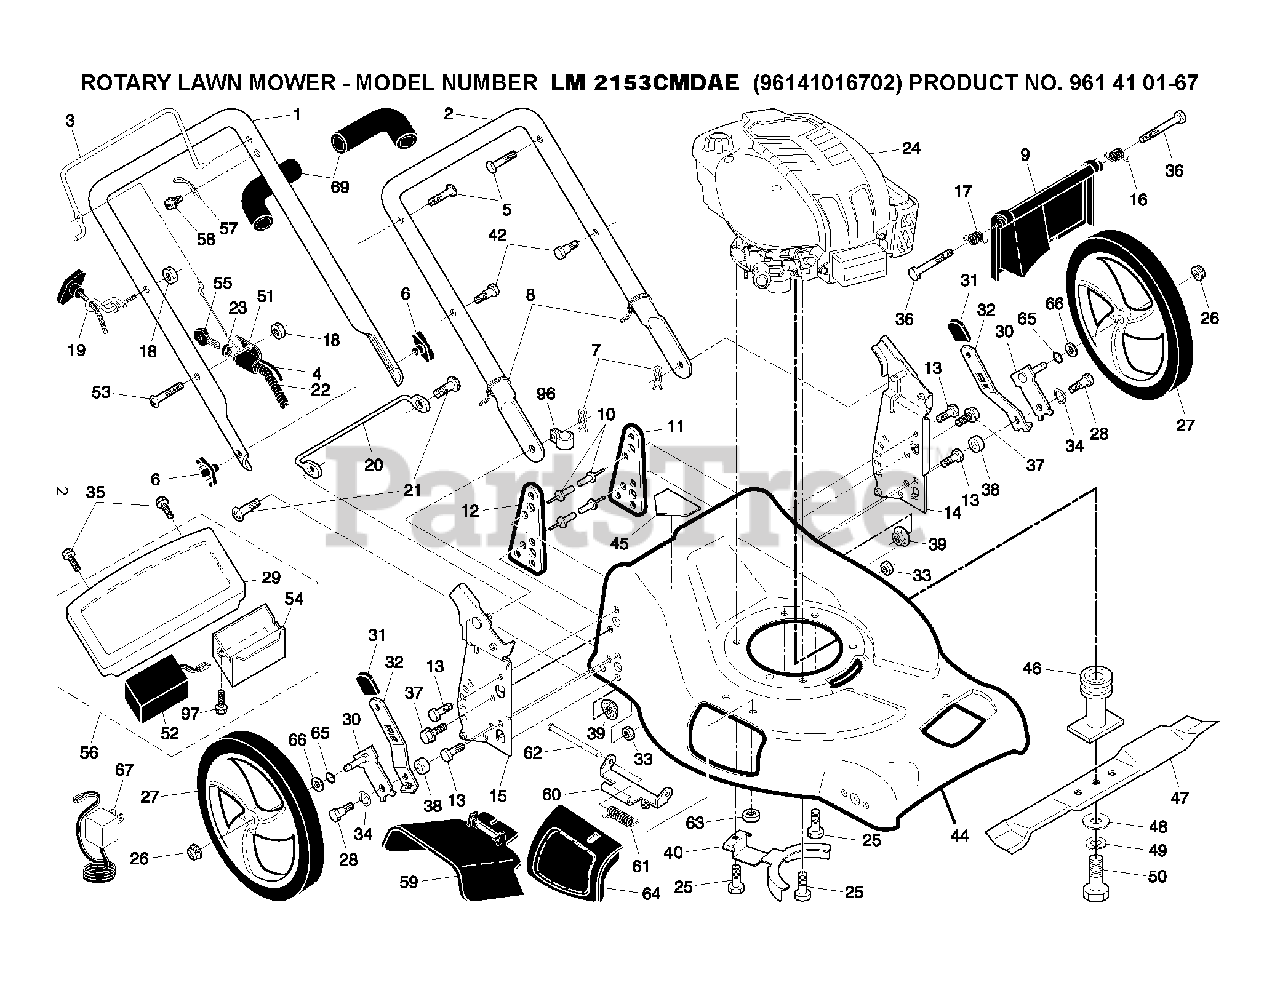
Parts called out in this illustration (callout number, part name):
4	CABLE, OPERATOR PRESENCE
5	BOLT, HANDLE 5/16-18X1.75
6	KNOB, DEFLECTOR
7	HAIRPIN COTTER
8	TIE GUIDE
9	REAR DOOR ASSEMBLY
10	RIVET BLIND
11	SUPPORT BRACKET LH
12	BRACKET.SUPRT.RH.21.FWGD
13	SCREW 14-20 X 5/8
14	HANDLE BRACKET ASSEMBLY, LEFT
15	HANDLE BRACKET ASSY. (RIGHT)
16	SPRING.REAR.DOOR.EZ.21.LT
17	SPRING.REAR.DOOR.EZ.21.RT
18	NUT
19	GUIDE.ROPE.STD.BLK.ZIN
21	SCREW
22	WIRING HARNESS
23	NUT.CAP.SNAP-ON.KEY START
25	BOLT 3/8-16X1-1/8
26	NUT.HEX.FLANGE.3/8-16.LOCKNUT
28	SHOULDER BOLT 5/16-18
29	PANEL.TRIM.21.FWGD.ES
30	ARM.ASM.AXLE.REAR.5/9.POS.BZP
31	SELECTOR KNOB
32	SELECTOR SPRING
33	NUT.71038.31-18.HEX.NYLOCK
34	WASHER FLAT
35	SCREW.PAN.HEAD.#10
37	BOLT
38	SPACER.HEIGHT.ADJUSTER
39	NUT.FLANGE.5/16
40	BELT KEEPER
42	SCREW.SHOULDER.HH.10X.281X.6
45	DECAL.INTERNATIONL.CUTFINGER
47	BLADE.21.PUSH
48	WASHER,HARDEN
49	LOCKWASHER
50	SCREW, HEX HD 3/8-24 X 1-3/8
51	KEY.START.CONTROL.W/ZONE
52	BATTERY.AMP.CONNECTOR
53	SCREW.(COMBINATION CONTROL)
54	BOX.BATTERY.TRIM
55	KEY.MOLDED
56	PANEL.ASM.TRIM/BATTERY.BOX
57	BRACKET UPSTOP
59	DISCHARGE DEFLECTOR
60	HINGE BRACKET ASSEMBLY
61	SPRING.TORSION
62	ROD.HINGE.21
63	LOCKNUT
64	DOOR.MULCH.21.REAR
65	O-RING..070X.487.NEOPRENE
66	WASHER PM
69	GRIP.HANDLE.FOAM.WIDE.(1 SIDE)
96	CLIP.CABLE.BLK
